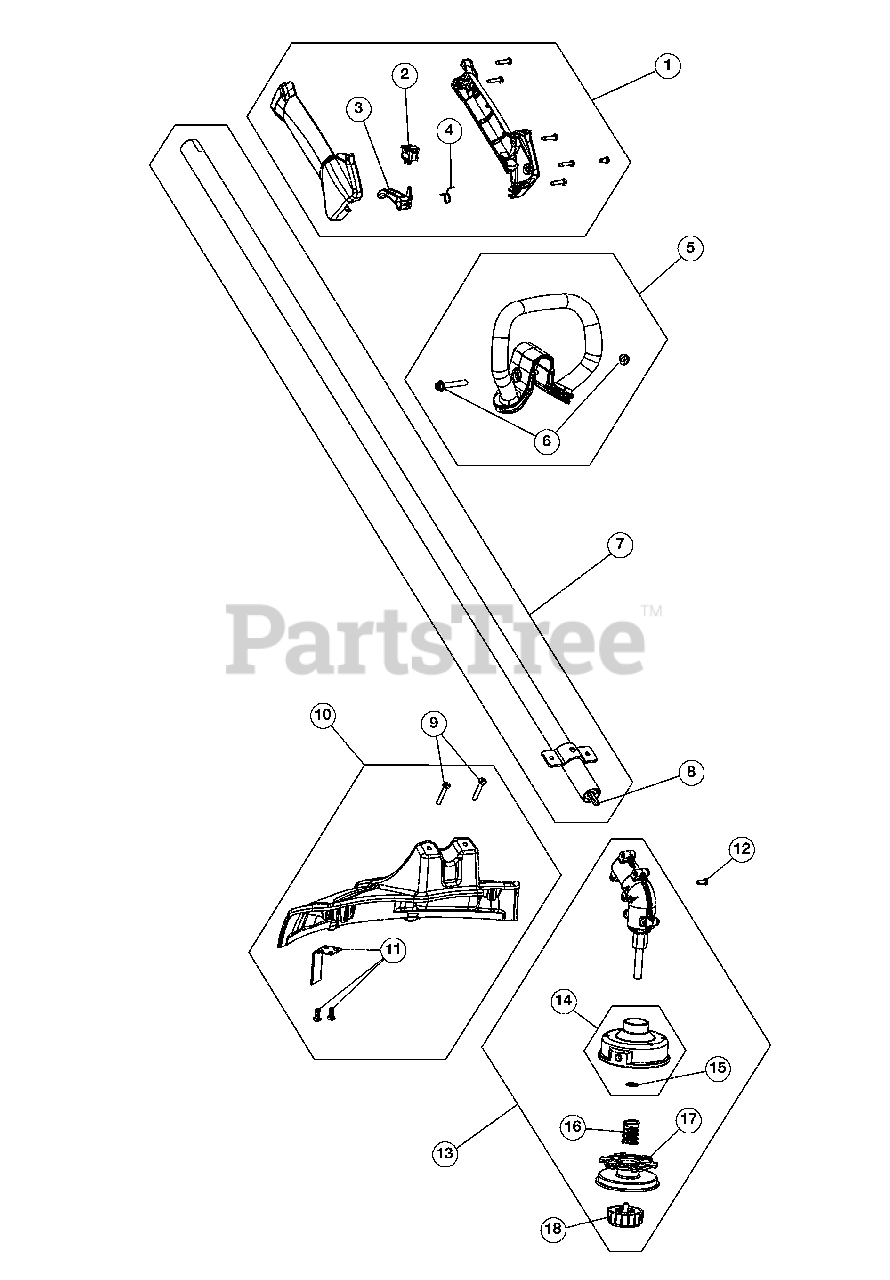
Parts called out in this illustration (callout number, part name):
1	Throttle Housing Assembly (Incl. 2-4)
3	Throttle Trigger
4	Throttle Trigger Spring
5	D-Handle (Incl. 6)
6	D-Handle Bolt
7	Drive Shaft Housing Assembly (Incl. 8)
8	Flexible Drive Shaft
9	Shield Mounting Screw
10	Shield Assembly (Incl. 9 & 11)
11	Blade Assembly
12	Anti-Rotation Screw
13	Gearbox Assembly (Incl. 14-18)
14	Outer Spool Assembly (Incl. 15)
15	Retainer
17	Inner Reel
18	Bump Head Knob Assembly
